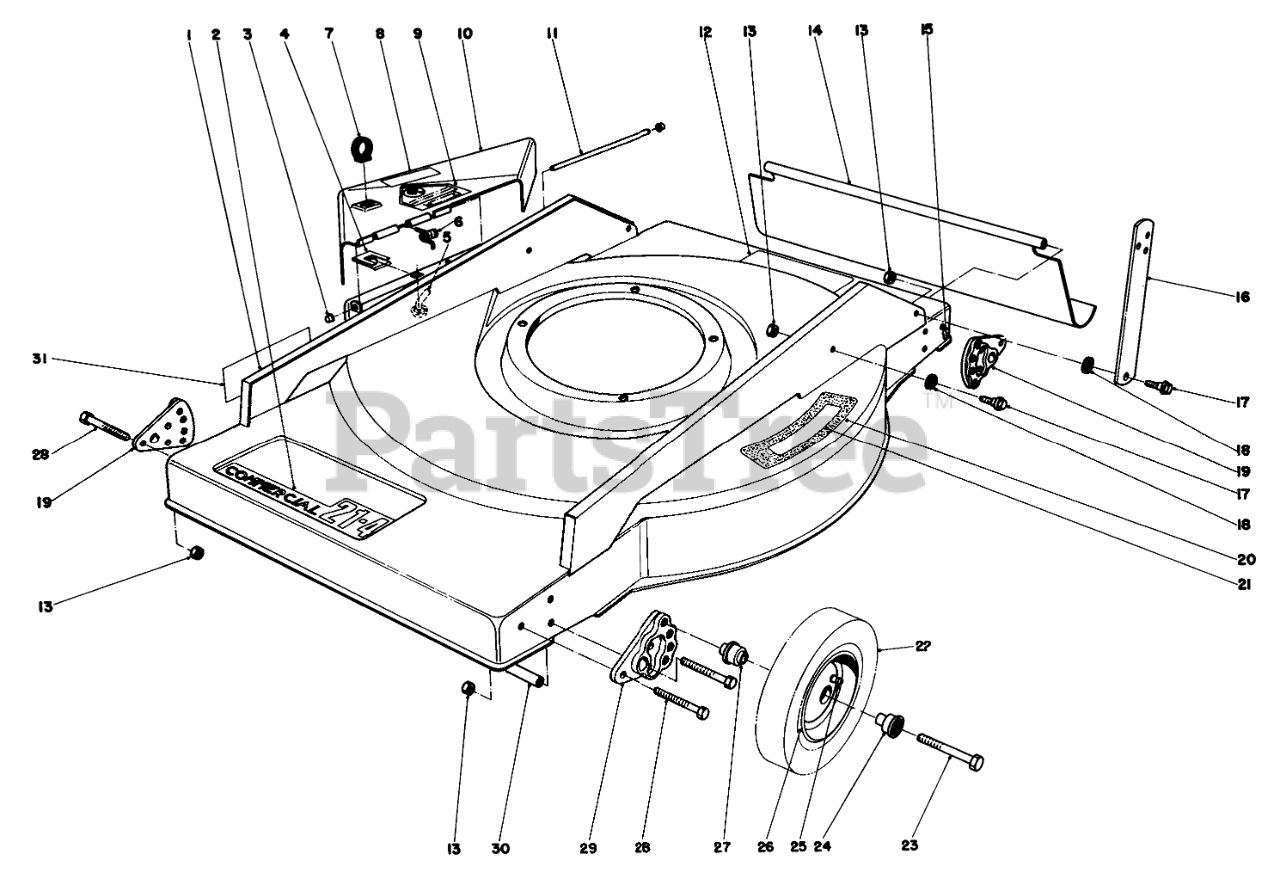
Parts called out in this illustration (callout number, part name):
1	Housing (Incl. Ref. #2, 12, 21 & 31)
2	Decal 214 Commercial
3	PUSHNUT-CAP, WASHER
4	BAG CHUTE CLIP PIN
5	BAG CHUTE PIN
6	TORSION SPRING
7	LIFT LOOP
8	DECAL DEFLECTOR
9	DECAL-DANGER
10	Deflector (Incl. Ref. #8 & 9)
11	DEFLECTOR PIVOT ROD
12	DECAL SAF INST
13	NUT-LOCK, CONE
14	REAR SAFETY SHIELD
15	SHIELD ROD
16	Handle Strap
17	SCREW-SHOULDER
18	HANDLE LATCH SPACER
19	Wheel Quadrant (B)
20	PAD STEP
21	Decal Step Pad
23	SCREW-HH
24	Bearing
25	FITTING-GREASE
26	Wheel 8" (Incl. Ref. #22, 24, 25 & 27)
27	Bearing
28	SCREW-HH
29	WHEEL QUADRANT (A)
30	Rod-Tie
31	DECAL CAUTION
